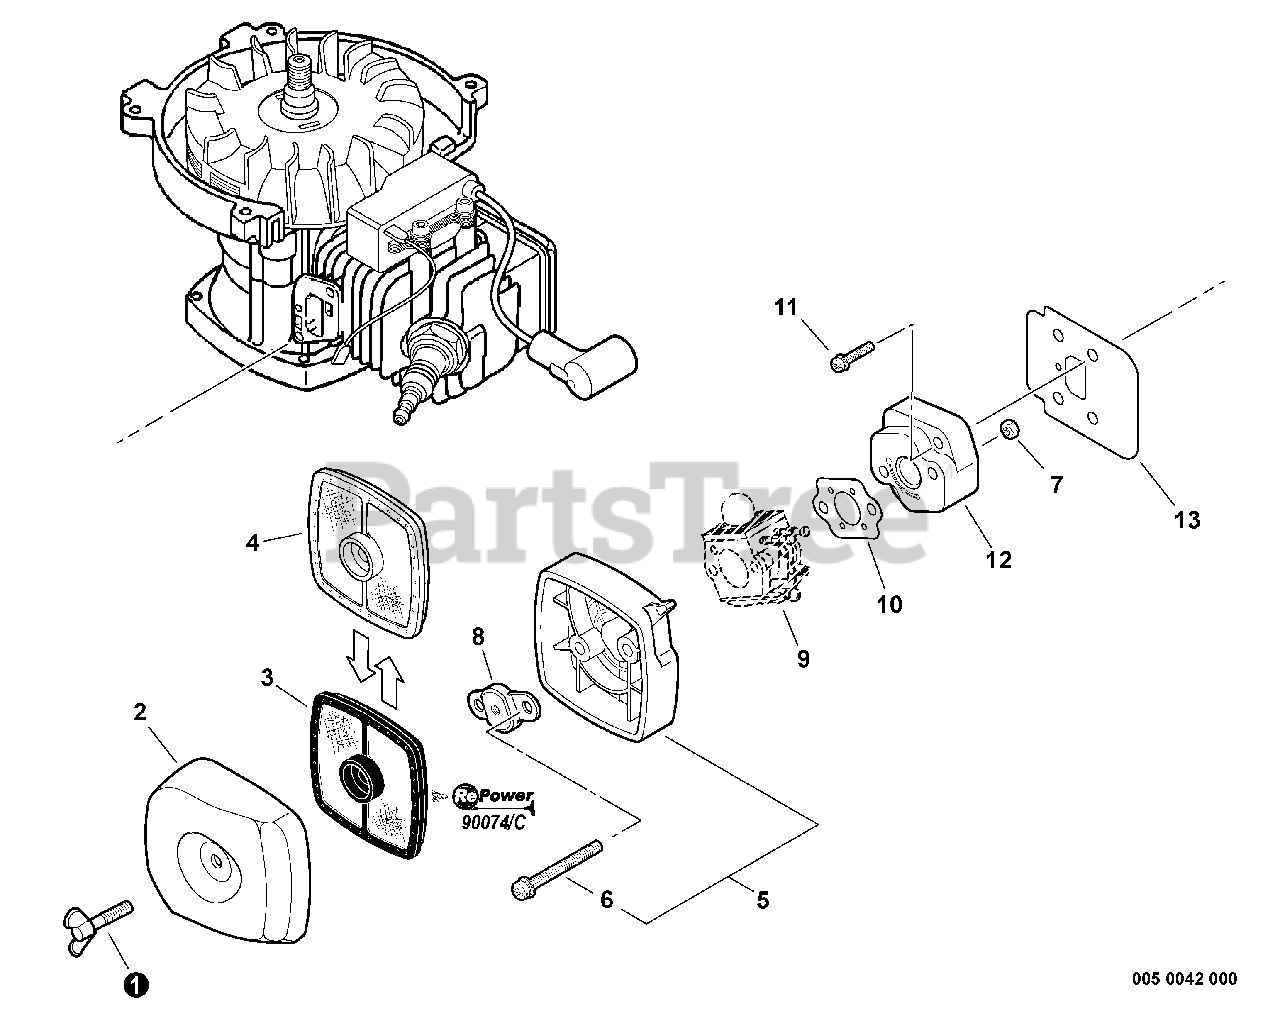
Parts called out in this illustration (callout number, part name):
1	BOLT, WING 5×20
2	COVER, AIR FILTER - GRAY
2	COVER, AIR FILTER - BLACK
3	FILTER, AIR - DOUBLE LAYER
4	FILTER, AIR - SINGLE LAYER
5	CASE, AIR FILTER - GRAY
5	CASE SET, AIR FILTER
6	SCREW 5×65
7	NUT M5
8	PLATE, PREVENT
9	CARBURETOR
10	GASKET, INTAKE
11	SCREW 5×20
12	INSULATOR, INTAKE
13	HEAT SHIELD, INTAKE
14	TUNE-UP KIT - REPOWER
